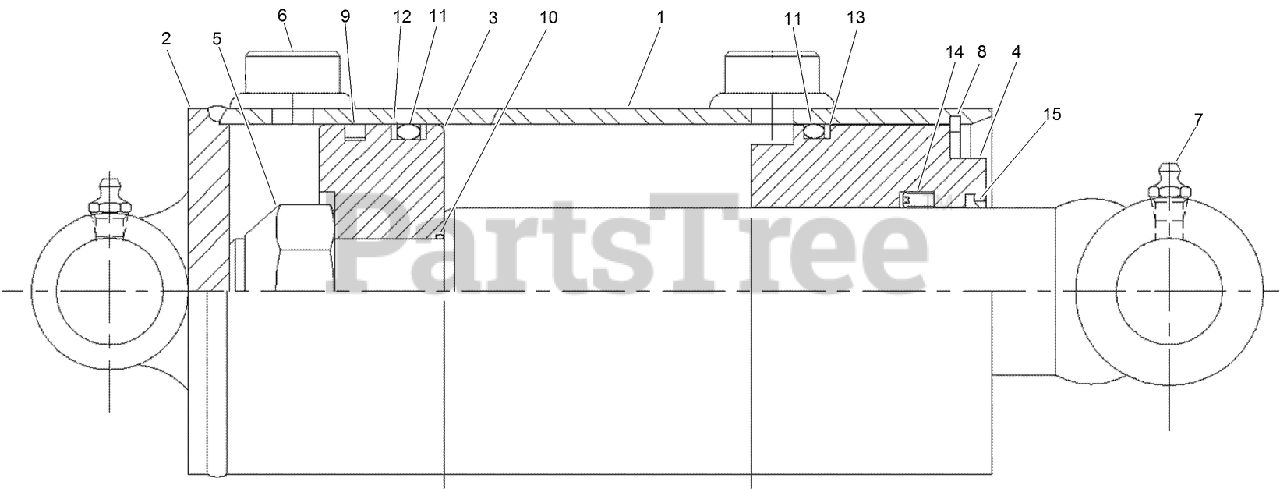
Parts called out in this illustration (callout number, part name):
1	ASSEMBLY - Piston Rod
2	ASSEMBLY - Butt & Tube
3	PISTON
4	GLAND
6	PLUG - Port
7	ZERK - Grease
8	RETAINER - Snap Ring
9	RING - Piston
10	O-RING
11	O-RING
12	WASHER - Back Up, Leather
13	WASHER - Back Up
14	CUP - U
15	WIPER
